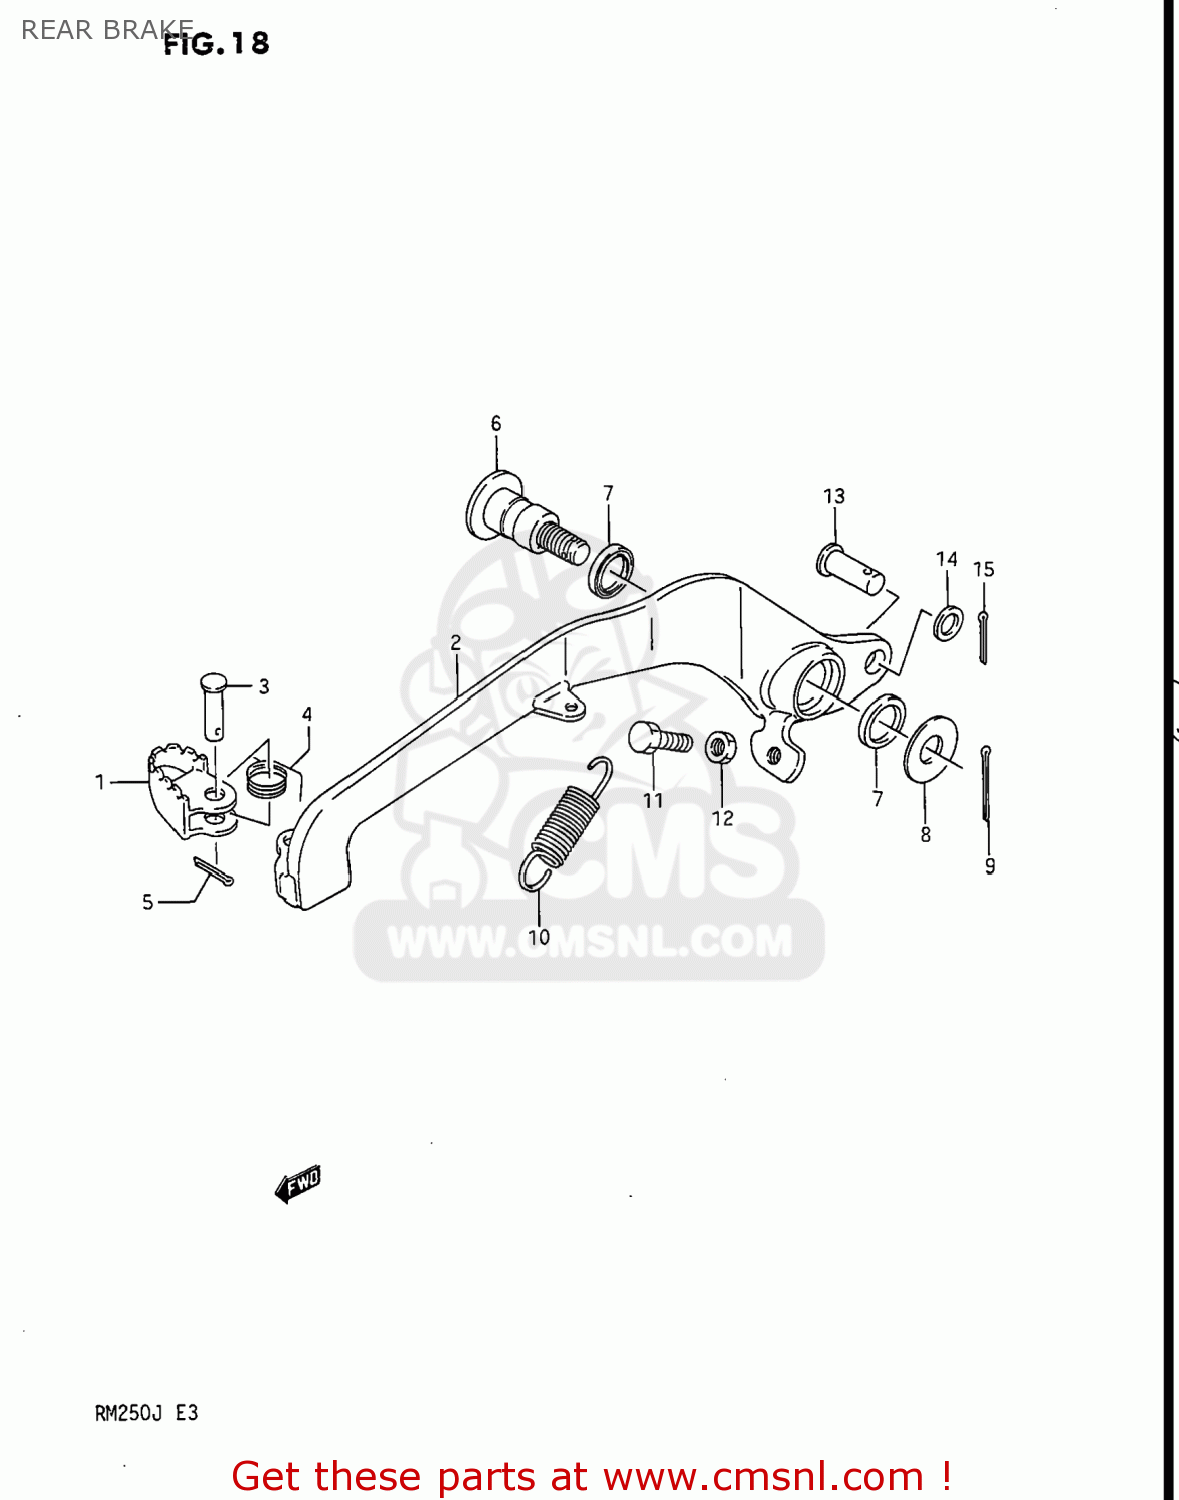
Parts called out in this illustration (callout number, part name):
1	PEDAL,BRAKE
2	ARM,BRAKE PEDAL
3	PIN
4	SPRING
5	PIN
6	SHAFT,BRAKE PEDAL
7	SEAL,OIL(15X20X3)
8	WASHER
9	PIN 20X20
10	SPRING
11	BOLT(6X23)
12	NUT 6MM
13	PIN(8X20)
14	WASHER(8.5X13X1.6)
15	PIN
